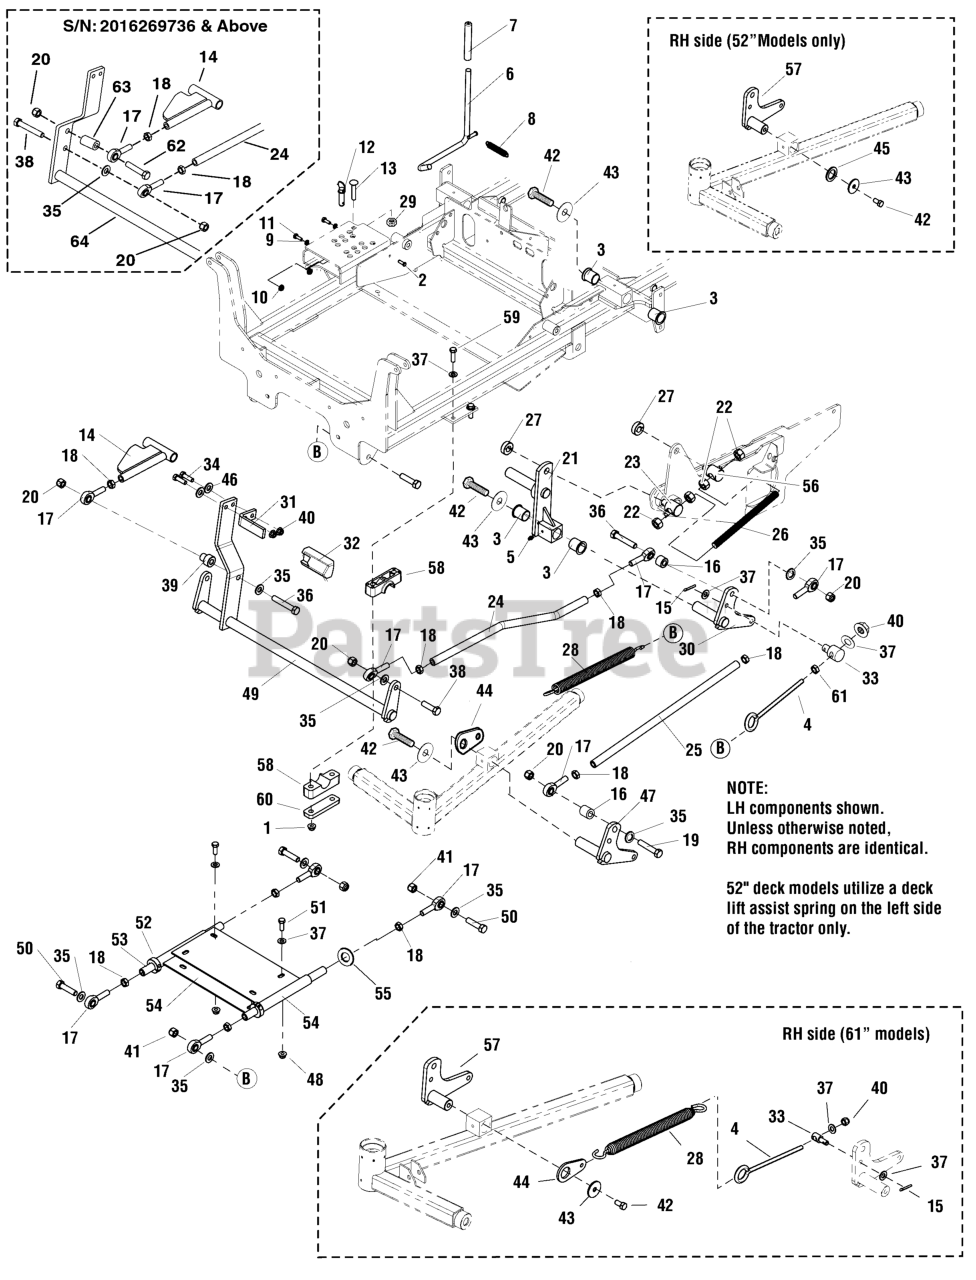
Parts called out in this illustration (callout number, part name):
1	NUT, 3/8-16 HEX NYLOCK FLANGE
2	PIN, CLEVIS, 1/4 X 7/8, PLATED
3	BUSHING, 1.00 X 1.13 X 1.38, PLASTIC
4	* EYEBOLT, 3/2-16 X 8", 1" EYE
5	GREASE FITTING, 1/4-28 STRAIGHT
6	WELD, ROD DECK LIFT - BLK
7	GRIP, FOAM
8	SPRING, EXTENSION
9	WASHER, 1/4 SAE
10	NUT, 1/4-20 HEX SERR. FLANGE
11	BOLT, 1/4-20 X 3/4" GD5 YZ
12	PIN, HITCH, 1/2 X 2.00 OAL, YP
13	BOLT, 3/8-16 X 2", CARRIAGE
14	WELD, DECK ADJUST LINK - RED
15	* PIN, COTTER, 1/8" X 3/4
16	SPACER, .52 X 1.00 X .75
17	BALL JOINT, 1/2-20, MALE
18	NUT, 1/2-20 HEX JAM
19	BOLT, 1/2-13 X 2-3/4 GD5 CZ
20	NUT, 1/2-13 HEX NYLON LOCK
22	NUT, 5/8-11 HEX
23	PIVOT, SPRING ROD
24	ROD, DECK LIFT BENT
25	ROD, DECK LIFT, OUTER
26	ROD, 5/8-11 X 9.00
27	COLLAR, 5/8" SPLIT
28	* SPRING, DECK LIFT ASSIST
29	NUT, 3/8-16 HEX SIDE LOCK
31	PEDAL, FOOT - BLK
32	PEDAL, Rubber
33	* ADJUSTER, DECK HANGER
34	BOLT, 3/8-16 X 1-1/4" GD5 CZ
35	WASHER, 1/2" SAE
36	BOLT, 1/2-13 X 3-1/2, HEX HD, GD5, CZ (SV)
37	WASHER, 3/8 SAE
38	BOLT, 1/2-13 X 1-3/4 GD5 CZ
39	ADAPTER, CASTER AXLE, CZ
40	NUT, 3/8-16 HEX NYLON LOCK
41	NUT, Hex, Nylon Lock, 1/2-20
42	WASHER, .390 X 1.50 X .109, YZ
43	BOLT, 3/8-16 X 3/4, PLT W/PATCH
44	* MOUNT, SPRING DECK LIFT - RED
45	SHIM, 1.0 X 1.5 X 0.125
46	WASHER, 3/8" GR9 FLAT
47	WELD, PIVOT DECK LIFT - LH - RED
48	NUT, 3/8-16 HEX SERRATED FLANGE
49	WELD, DECK LIFT SHAFT - RED
50	BOLT, 1/2-20 X 1-3/4" GD8 CZ
51	BOLT, 3/8-16 X 1" GD5 CZ
52	COLLAR, 3/4" SPLIT
53	SHAFT, DECK STABILIZER
54	WELD, DECK STABILIZER - BLK
55	WASHER, 1/2 SAE
57	WELD, PIVOT DECK LIFT - RH - RED
58	PIVOT BLOCK, PLASTIC
59	BOLT, 3/8-16 X 2-3/4" GD5 CZ
60	PLATE, PIVOT BLOCK SUPPORT - BLK
61	NUT, 3/8-16 HEX
62	BOLT, 1/2-13 X 4" GD5 CZ
63	SPACER, .52 X 1.00 X 1.75
64	WELD, DECK LIFT SHAFT - RED
